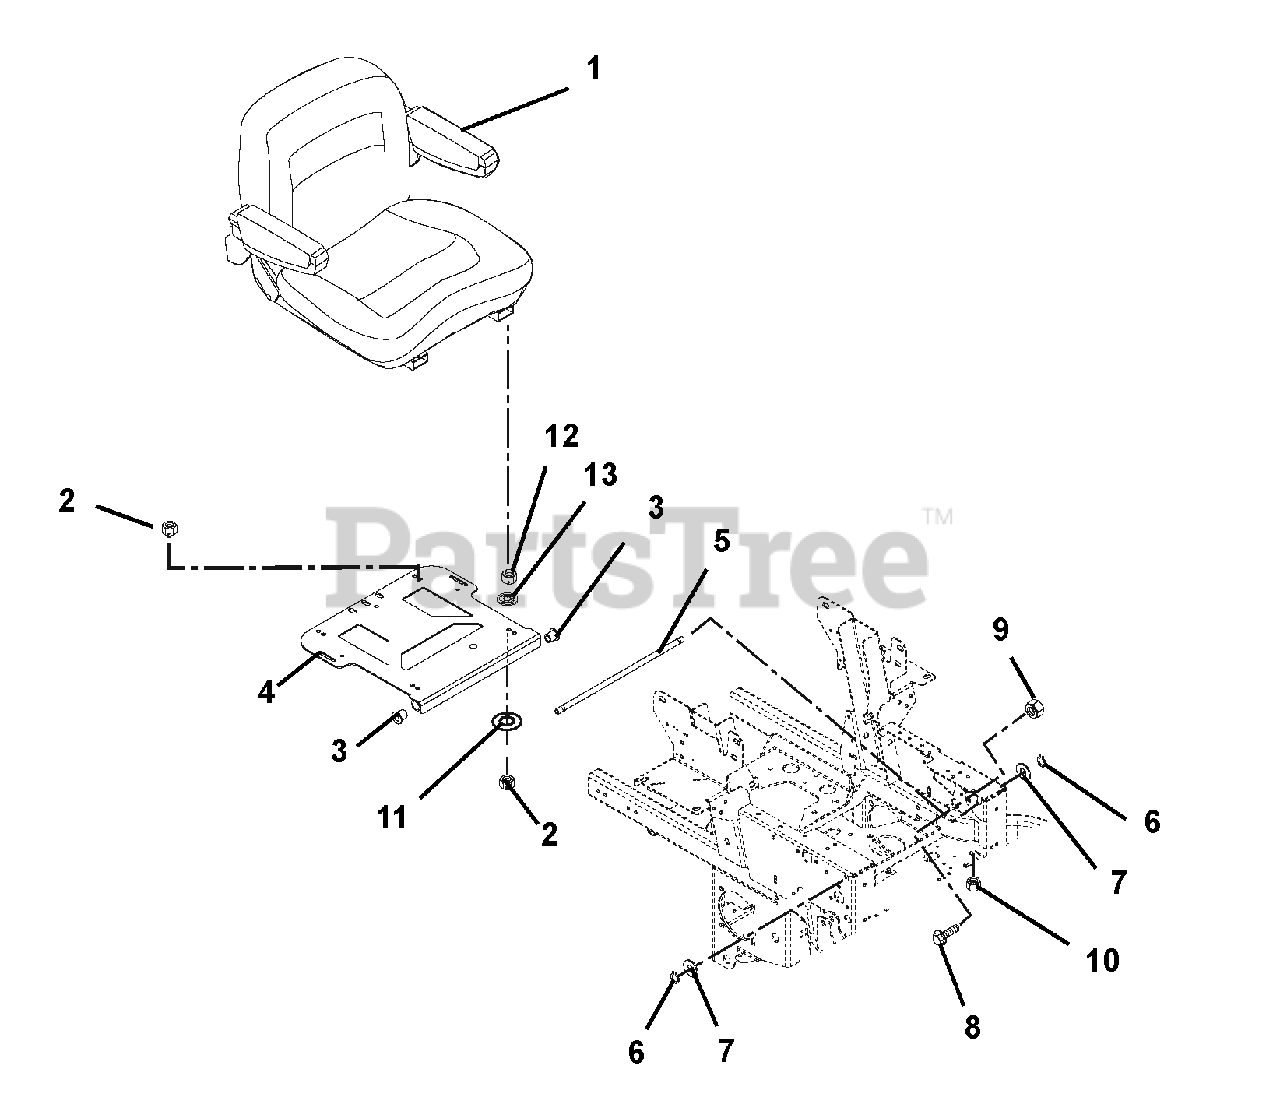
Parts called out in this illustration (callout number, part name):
1	SEAT
2	@NUT-LK-TOP-FLG .31-18 YWZC
3	BSHG-FLG .515X.750X.745X1.00NY
4	WMT, SEAT PLATE
5	ROD, SEAT FRAME PIVOT
6	RG-RTNG-EXT .500X.050 (SNAP)
7	WSHR-FL-STL.531X1.00X.063 YWZC
8	FITTING, BARBED
9	@NUT-LK-CTR .38-16 YWZC
10	@NUT-LK-TOP-FLG .25-20 YWZC
11	@WSHR-FL-STL.38X.875X.083 YWZC
12	BSHG-SLV .377X.624X.235
13	NUT-PUSH .312
